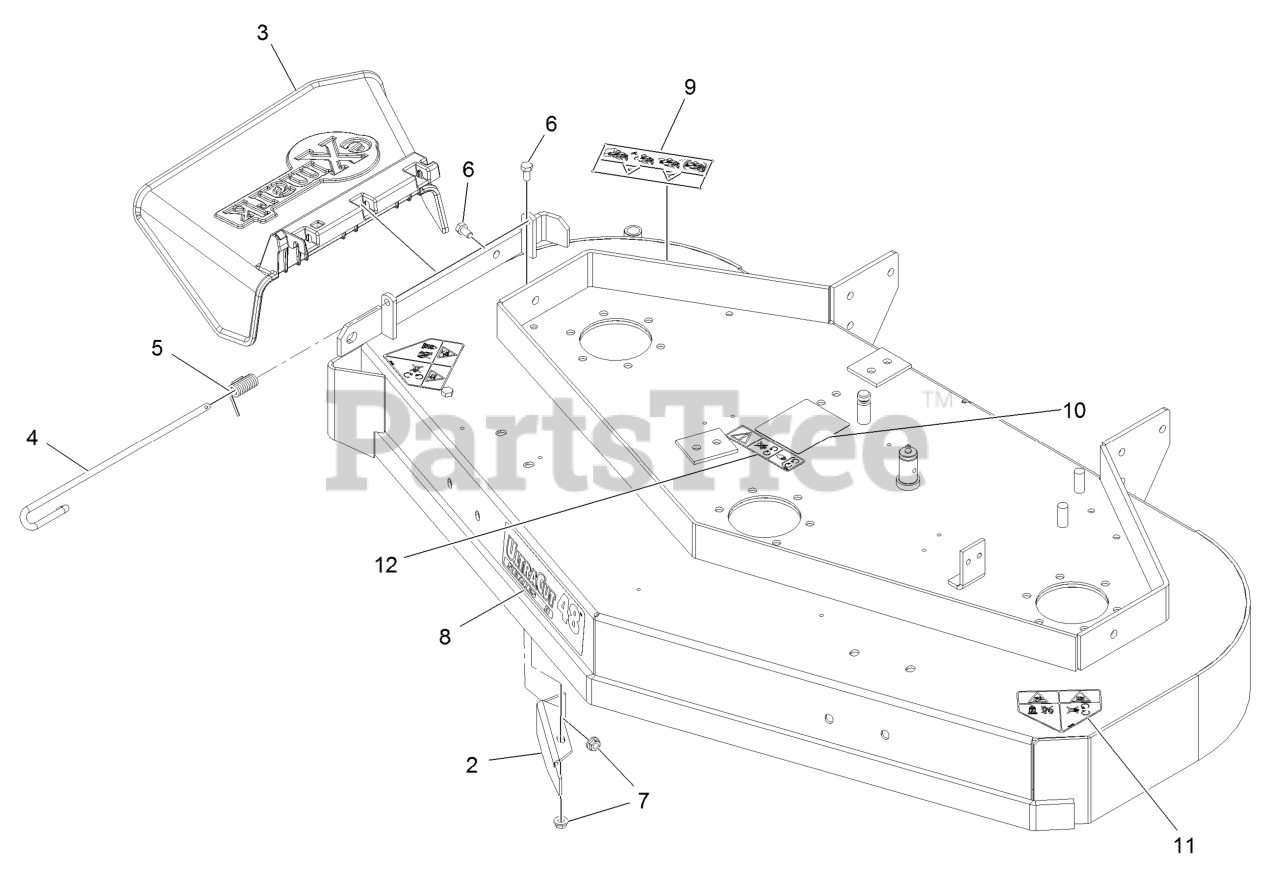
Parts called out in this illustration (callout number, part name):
2	BAFFLE-DOGLEG
3	CHUTE DEFLECTOR XRK M056
4	PIN-CHUTE
5	SPRING, TORSION
6	SCREW-HH
8	DECAL-ULTRACUT 48 SERIES
9	DECAL-WARNING, BAGGER
10	DECAL-ROUTING, BELT
11	DECAL-DANGER
12	DECAL-COVER, MISSING
